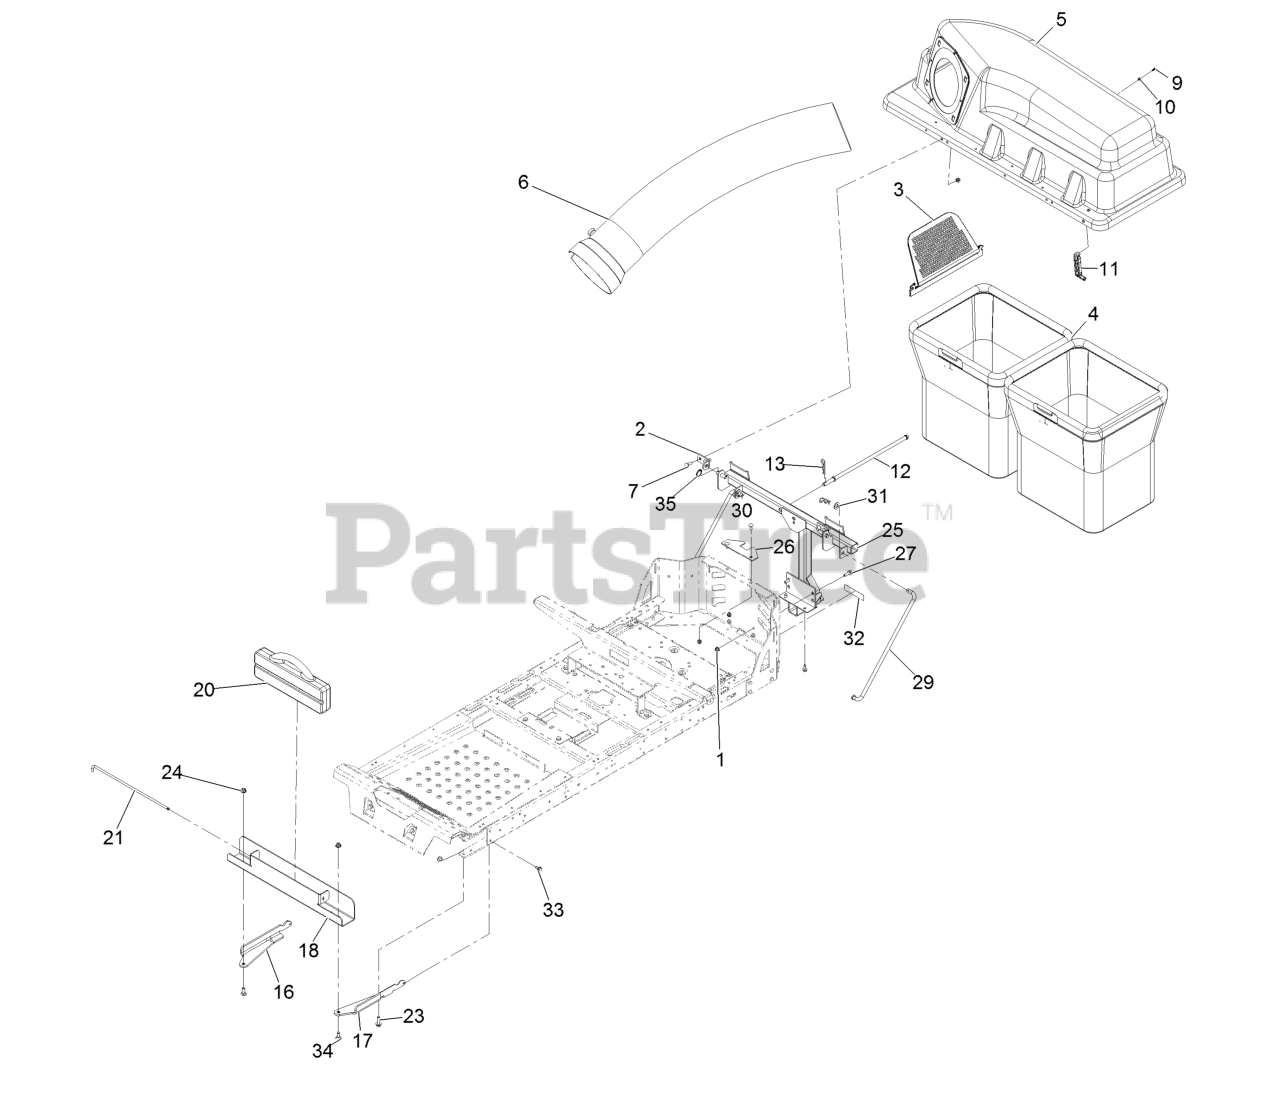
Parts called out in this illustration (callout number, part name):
1	NUT-HF, NI
2	BRACKET-PIVOT, HOPPER
3	SCREEN-BAGGER
4	BAG ASM
5	BAGGER TOP ASM
6	TUBE-BAGGER
7	BOLT-CARR
9	SCREW-PLASTIC, PTH
10	WASHER-FLAT
11	LATCH-RUBBER
12	ROD-HOOD, DOWN (HOLD)
13	PIN-HAIR
16	BRACKET-WEIGHT, RH
17	BRACKET-WEIGHT, LH
18	CHANNEL-WEIGHT, BAGGER
20	WEIGHT-35 POUND
21	PIN-WEIGHT
23	SCREW-HHF
24	NUT-HF, NI
25	FRAME-PIVOT
26	BRACKET-STABILIZER
27	SCREW-HHF
29	ROD-SUPPORT
30	BOLT-CARR
31	WASHER-FLAT
33	Screw-HWH 5/16-18 X 3/4 Tf
34	BOLT-CARR
35	PIN-COTTER, CIRCULAR
